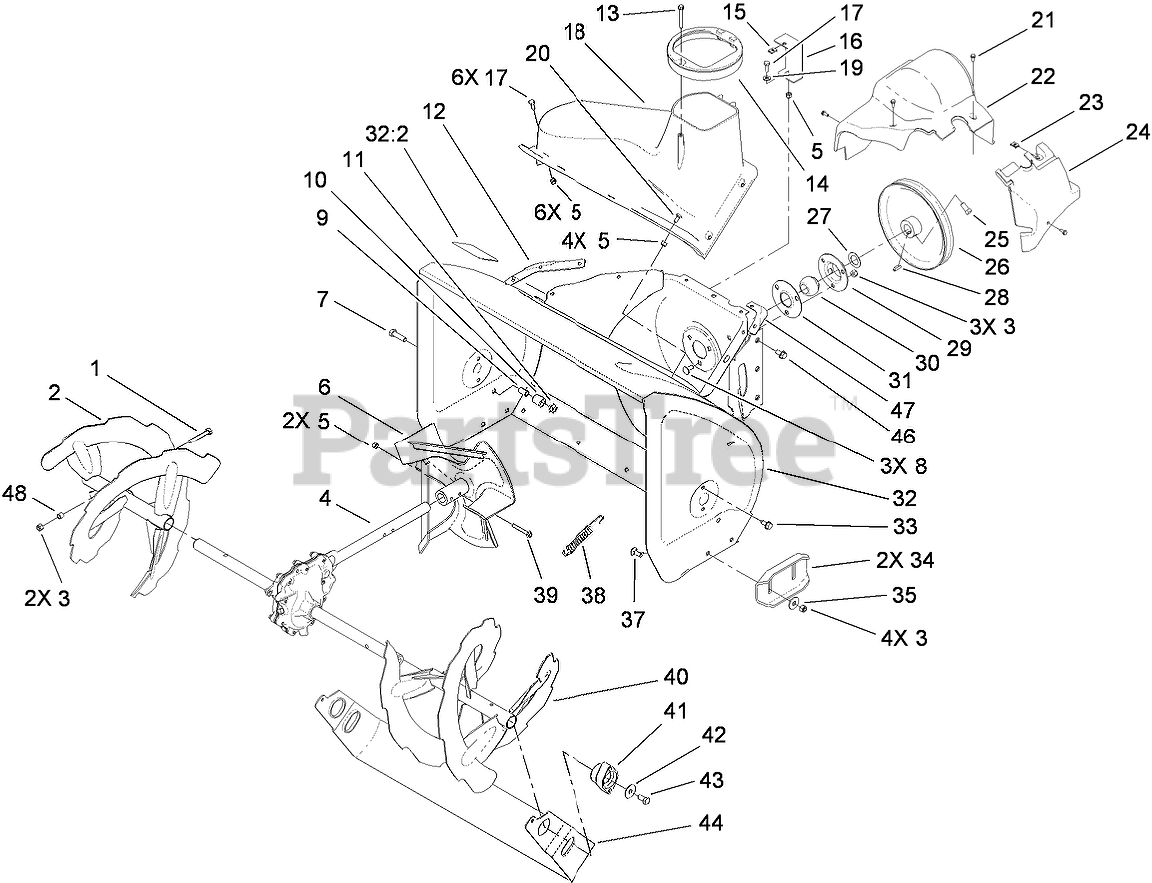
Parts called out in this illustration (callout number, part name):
1	SCREW-HH
2	RH AUGER ASM
3	NUT-LOCK, NI
4	28 INCH AUGER GEARCASE ASM
5	NUT-LOCK, NI
6	IMPELLER ASM
7	SCREW-HH
8	SCREW-CARR
9	SPACER-SCRAPER, STOP
10	CUSHION-SCRAPER, STOP
11	NUT-HF
12	SEAL-FLANGE, COVER
13	SCREW-PLASTITE
14	GUIDE-CHUTE
15	NUT-SPEED, U-TYPE
16	BRACKET-COVER, CLIP NUT
17	SCREW-HH
19	WASHER-FLAT
20	BOLT-CARR
21	SCREW-HWH
22	COVER-BELT
23	NUT-SPEED
24	COVER-EXTENSION, BELT
25	SCREW-SET, SQH
26	PULLEY-IMPELLER
27	WASHER-THRUST
28	KEY-WOODRUFF
29	FLANGE-CUP, BEARING
30	BEARING-BALL
31	FLANGE-CUP, BEARING
32	HOUSING-AUGER, 28 INCH
32:2	DECAL-DANGER, AUGER
33	SCREW-HWHTF
35	WASHER
37	SCREW-CARR
38	SPRING-SCRAPER
39	SCREW-HHF
40	LH AUGER ASM
41	BEARING-AUGER
42	WASHER
43	SCREW-HH
44	SCRAPER-PIVOTING, 28 INCH
46	SCREW-HWHTF
48	SPACER
